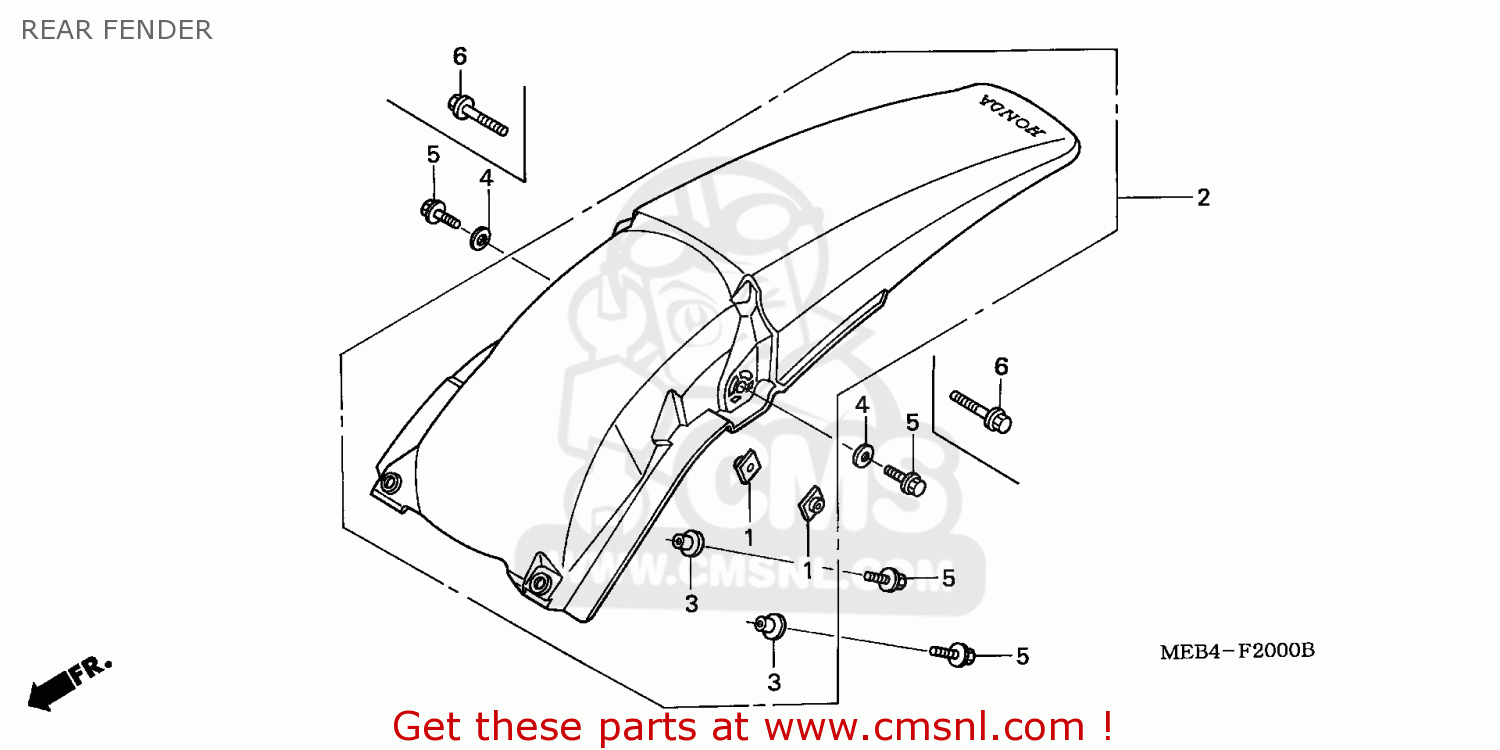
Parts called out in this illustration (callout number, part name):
1	NUT,SPECIAL,6X7
2	FENDER SET, RR. (WL)
3	COLLAR,A
5	BOLT,FLANGE,SH,6X16
